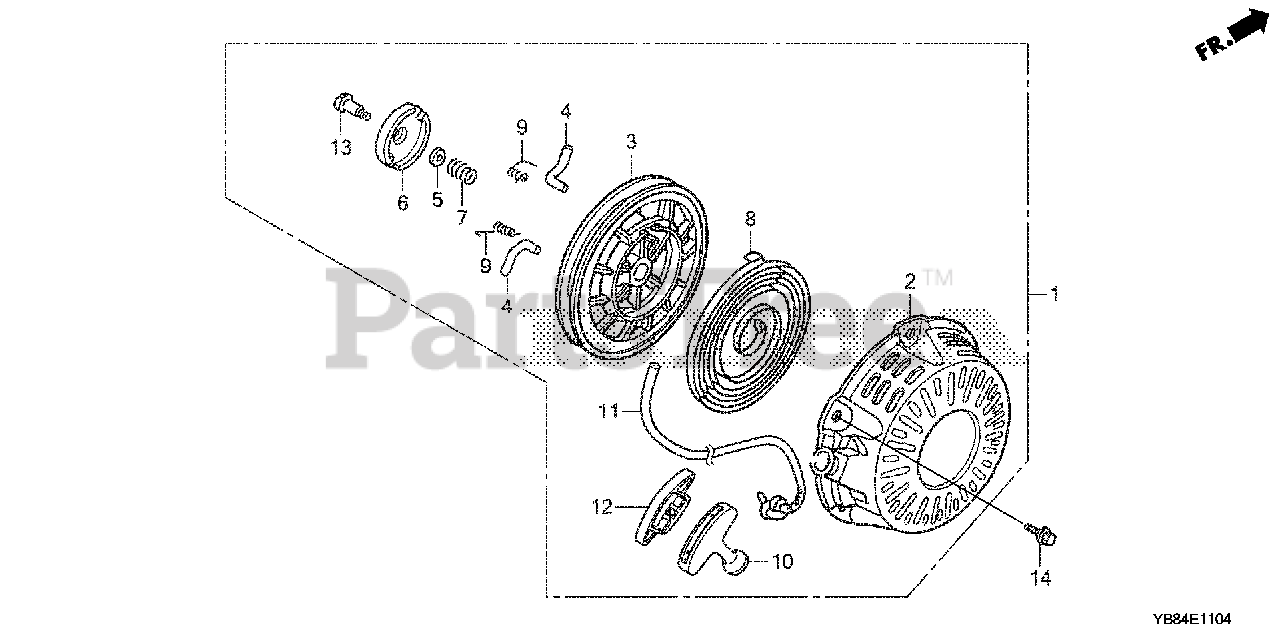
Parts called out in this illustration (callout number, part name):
1	STARTER ASSY., RECOIL *R280* (COO)(FOR U.S.A.) (POWER RED)
2	CASE, RECOIL STARTER *R280* (POWER RED)
3	REEL, RECOIL STARTER
4	RATCHET, STARTER
5	PLATE, FRICTION
6	GUIDE, RATCHET
7	SPRING, FRICTION
8	SPRING, RECOIL STARTER
9	SPRING, RETURN
10	KNOB, RECOIL STARTER (COO)(FOR U.S.A.)
11	ROPE, RECOIL STARTER
12	KNOB, REINFORCEMENT
13	SCREW, SETTING
14	BOLT, FLANGE (6X10)
